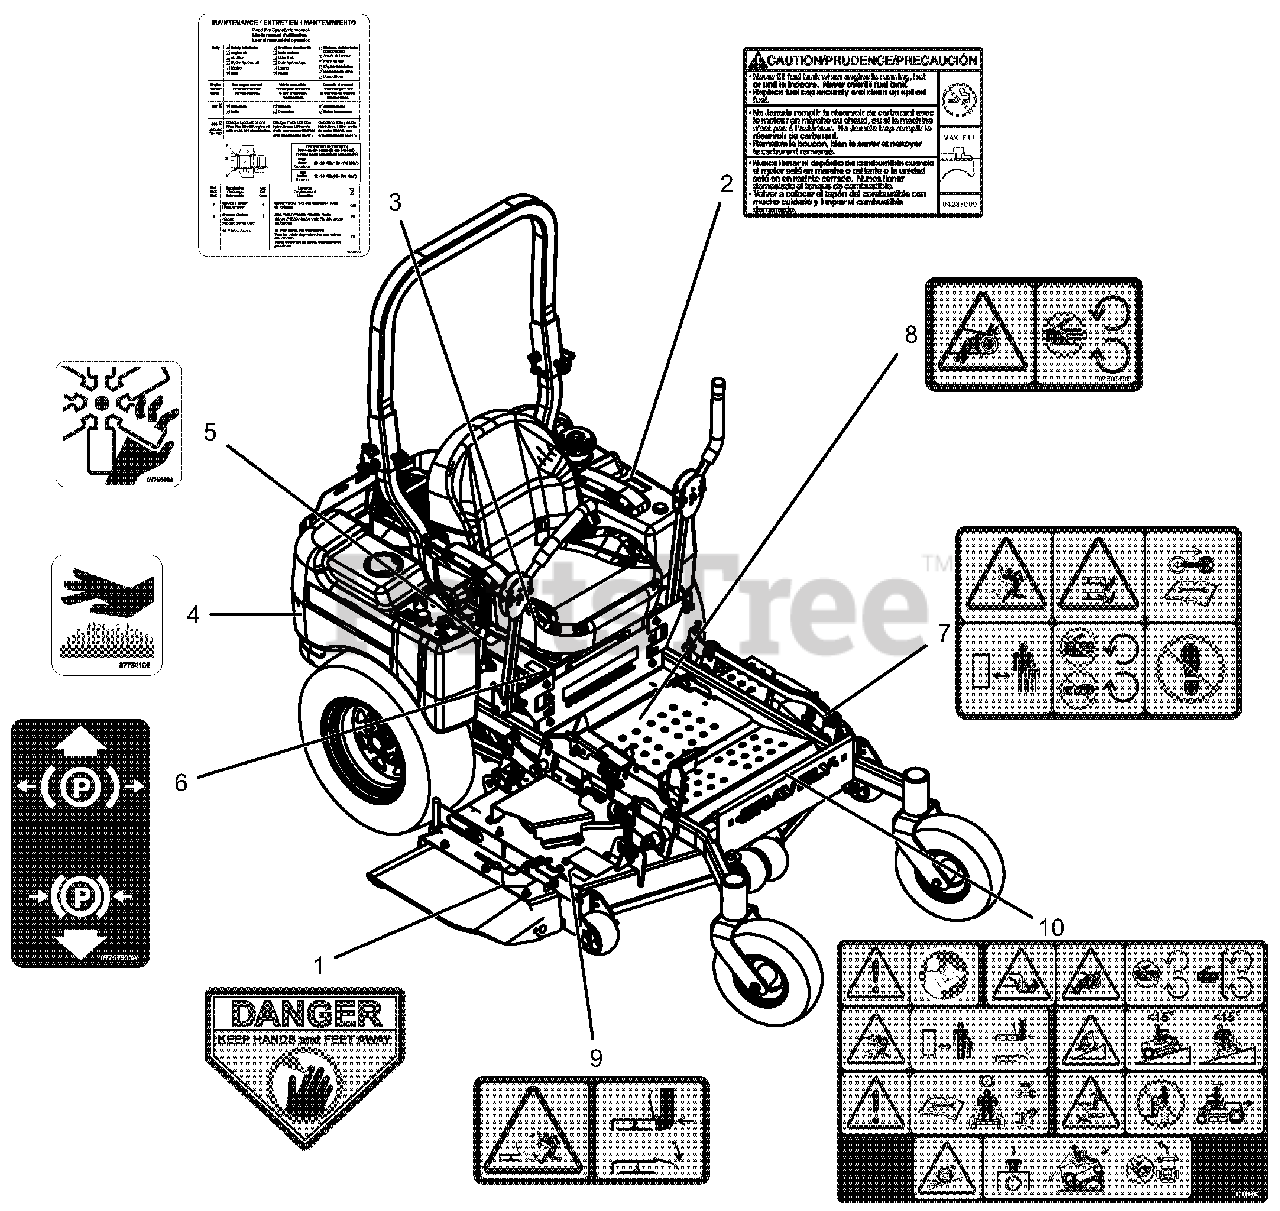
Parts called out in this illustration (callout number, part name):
1	DECAL, DANGER
2	DECAL, FUEL WARNING
3	DECAL, MAINTENANCE INSTRUCTIONS
4	DECAL HOT SURFACE
5	DECAL, DANGER - FAN
6	DECAL, PARKING BREAK LEVER
7	DECAL, SAFETY - MOWER DECK
8	DECAL, SAFETY - GUARDING
9	DECAL, SAFETY - DECK GUARDING
10	DECAL, MAIN SAFETY, COMMERCIAL
